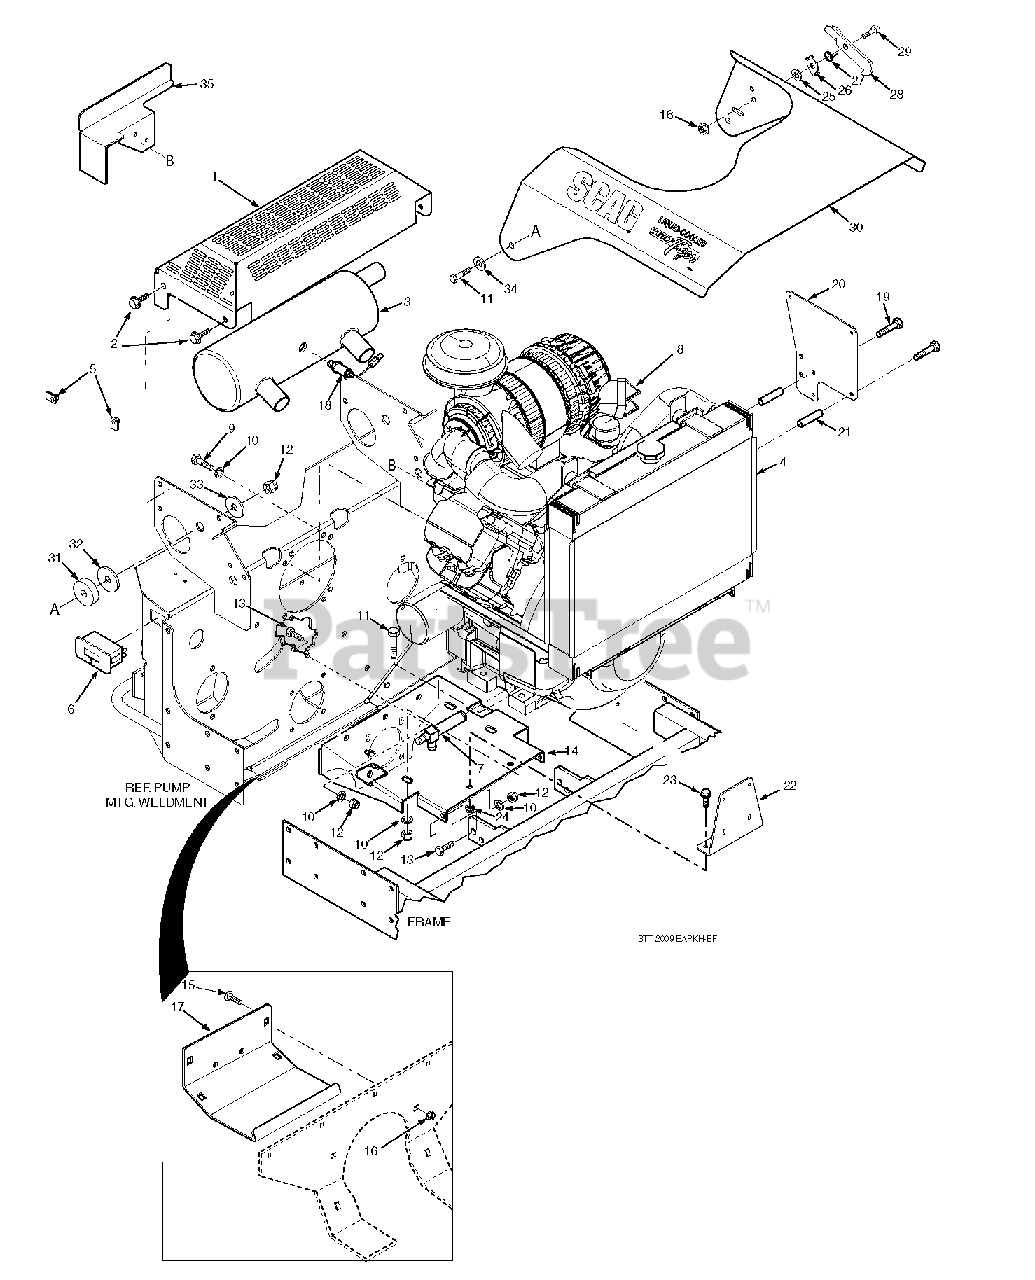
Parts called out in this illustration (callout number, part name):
1	Muffler Guard
2	Screw, Hex Serr. Flng. 1/4-20 x 3/4"
3	Muffler
4	Screen Weldment, Radiator
5	U-Nut, 1/4-20
6	Hour Meter
7	Oil Drain Extension
8	Engine, Kohler 31HP-EFI Aegis
9	Bolt, Hex Hd. 3/8-16 x 1"
10	Lockwasher, 3/8" Spring
11	Bolt, Hex Hd. 3/8-16 x 1-3/4"
12	Nut, Hex Elastic Stop 3/8-16
13	Bolt, Hex Hd. 3/8-16 x 1-1/4"
14	Plate, Engine Mounting
15	Bolt, Carriage 5/16-18 x 3/4"
16	Nut, Hex Serr. Flng. 5/16-18
17	Rear Cover
18	o2 Sensor
19	Bolt, Hex Hd. M6-1.0 X 90mm
20	Mounting Bracket, ECU
21	Spacer, ECU Mounting
22	Mounting Bracket, Fuel Pump
23	Bolt, Hex Hd. 1/4-20 x 3/4"
24	Nut, Serr. Flng. 1/4-20
25	Flatwasher, 3/8-.406 x .812 x .065
26	Lock, Hood Latch
27	Spring, Hood Latch
28	Latch, Hood
29	Bolt, Shoulder 5/16-18 x 1/2"
30	Hood Assembly w/Decals
31	Spacer, Hood
32	Disc, Anti-Friction
33	Flatwasher, 3/8-.406 x 1.50 x 7 Gauge
34	Flatwasher, 3/8-.391 x .938 x .105
35	Heatshield, Throttle Cable
